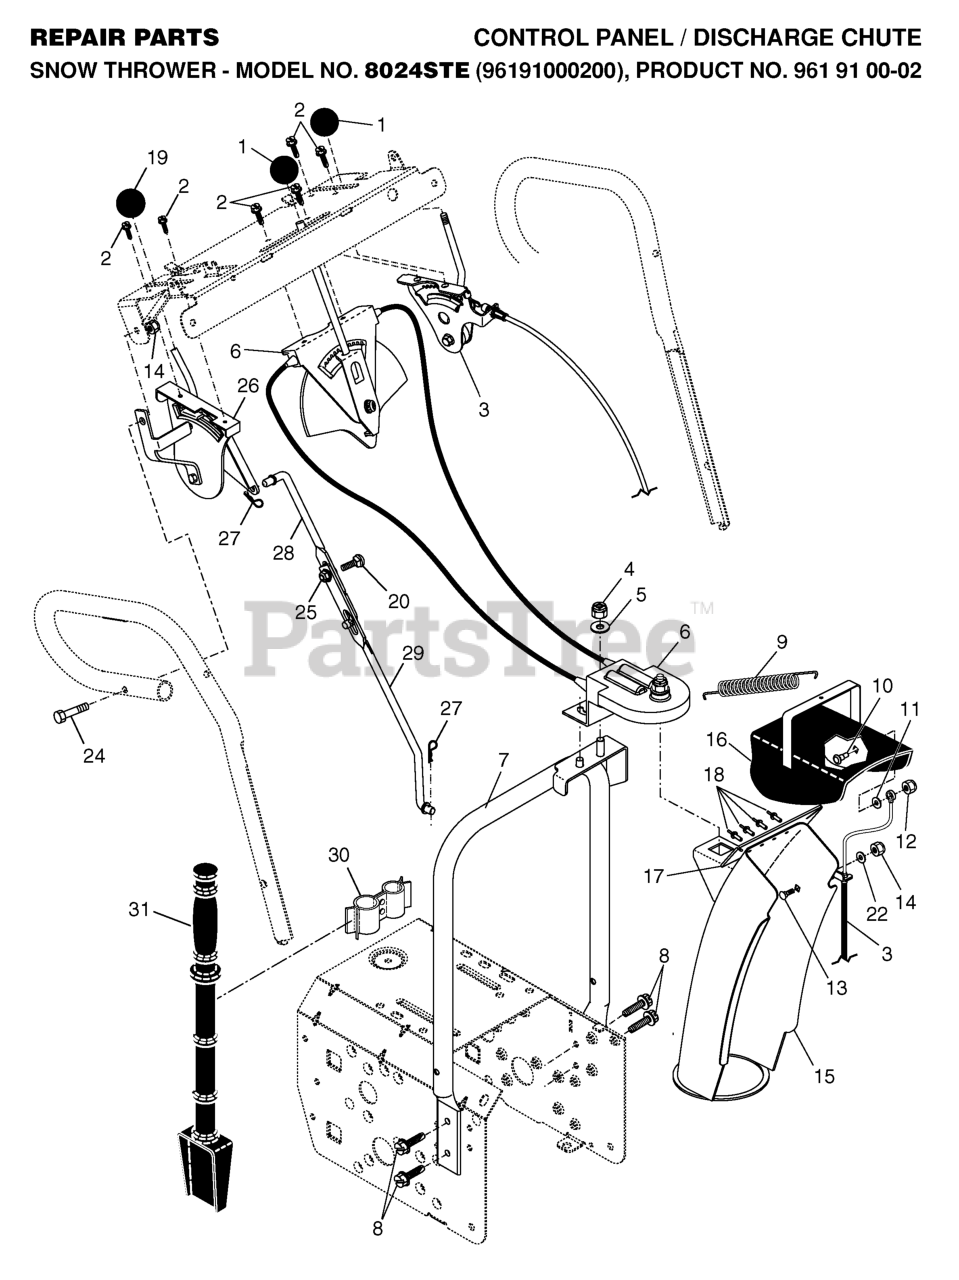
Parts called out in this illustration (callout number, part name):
1	KNOB, LEVER
2	SCREW #10-24 X 5/8
3	CONTROL ASSY, DEFLECTOR
4	NUT
5	WASHER
6	CONTROL ASSY, CHUTE ROTATER
7	SUPPORT CHUTE ROTATER
8	SELF-TAPPING SCREW 5/16-18X3/4
9	SPRING.DEFLECTOR.REM.CHUTE
10	BOLT, SHOULDER
11	WASHER, NYLON FRICTION
12	LOCKNUT.NYLOC.1/4-20
13	BOLT
14	NUT.71038.31-18.HEX.NYLOCK
15	CHUTE ASSY
16	DEFLECTOR.WELDMENT.PNT.ORANGE
17	SEAL, DEFLECTOR
18	RIVET BLIND
19	RP KNOB, SPEED CONTROL LEVER
20	BOLT
22	WASHER.20X8.5
25	NUT.FLANGE.5/16
26	HEAD ASSY SPEED
27	SPRING RETAINER
28	ROD, UPPER SPEED CONTROL
29	ROD, LOWER SPEED CONTROL.SNOW
30	CLAMP.ASM.CLEANOUT.TOOL.SNOW
31	CLEAN OUT TOOL
